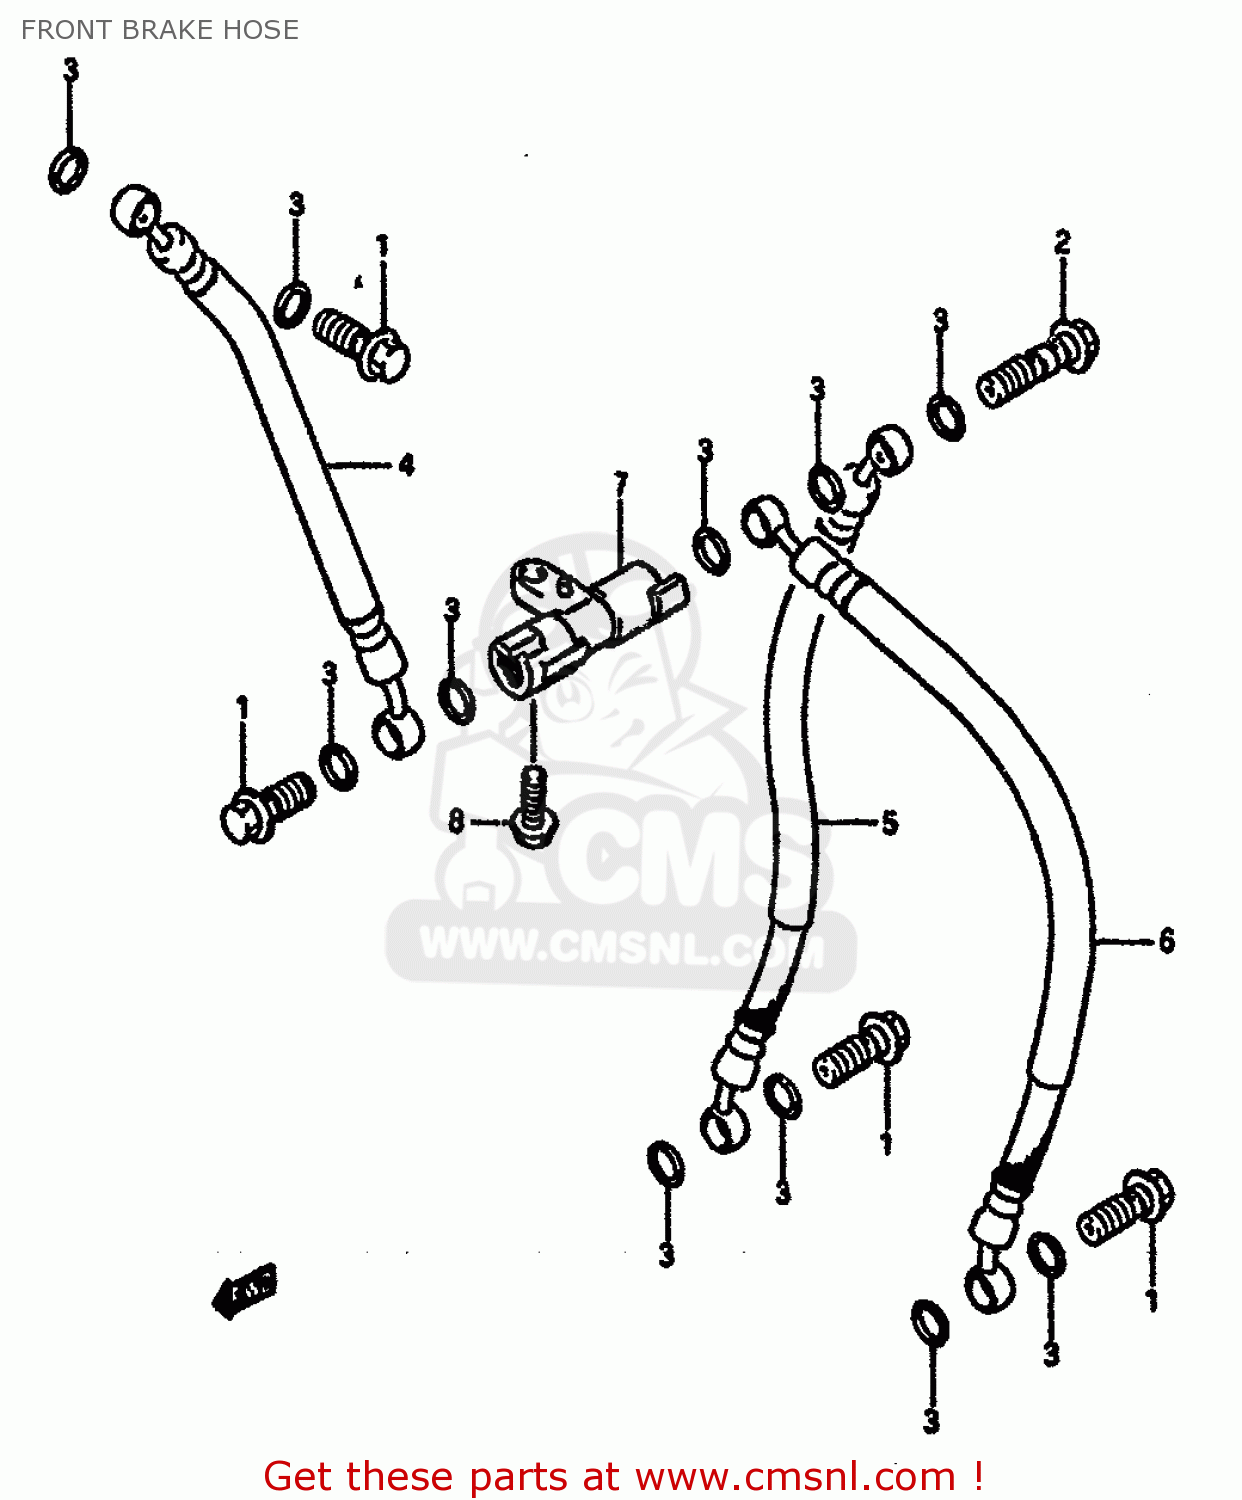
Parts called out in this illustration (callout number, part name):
1	BOLT UNION
2	BOLT UNION
3	WASHER(10X15X1.5)
4	HOSE,FRONT BRAKE NO.1
5	HOSE,FRONT BRAKE NO.2 RH
6	HOSE,FRONT BRAKE NO.2 LH
7	JOINT,BRAKE HOSE
8	BOLT 6X16
